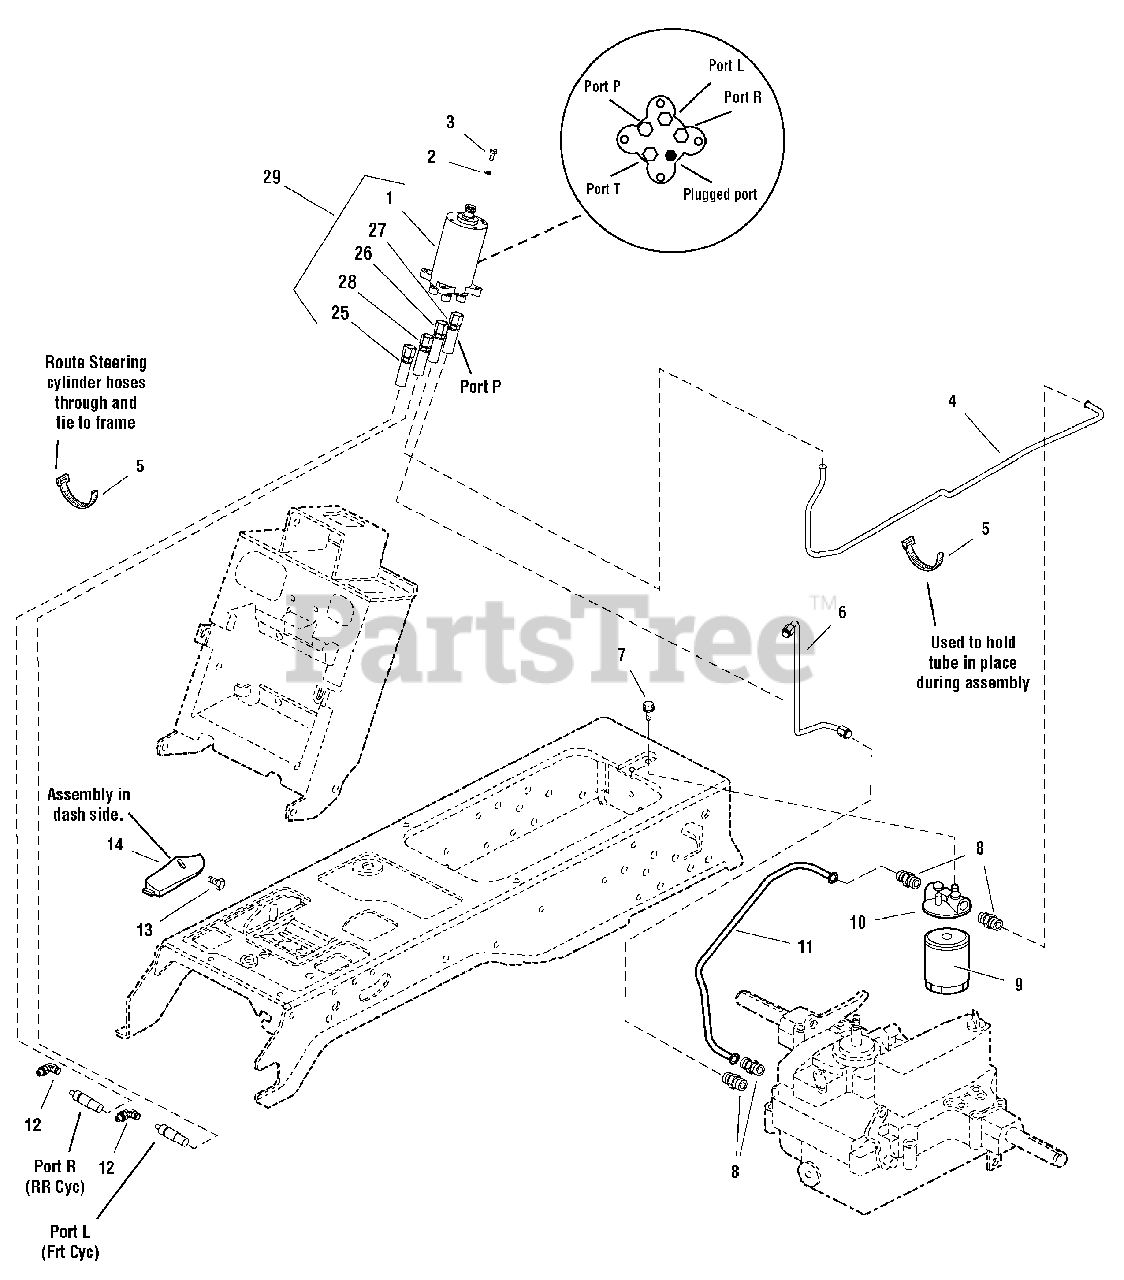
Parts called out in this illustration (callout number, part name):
1	POWER STEERING UNIT, 32CC, 4 Ports
2	LOCKWASHER, Spring
3	CAPSCREW, Hex Head
4	TUBE, Hydraulic
5	TIE, Self Locking
6	TUBE, Hydraulic
7	SCREW, Hex Whiz Lock Flange 1/4-20 x 1/2
8	FITTING, Straight
9	FILTER, Oil
10	BASE, Oil Filter
11	TUBE, Hydraulic
12	FITTING, Hose Elbow Perma Push 9/16-18
13	SCREW, Round Head Plastite
14	COVER, Lift
25	HOSE ASSEMBLY, 50"
26	HOSE ASSEMBLY, 18"
27	HOSE ASSEMBLY, 26"
28	HOSE ASSEMBLY, 46"
29	POWER STEERING ASSEMBLY, 32CC, 4 Ports
29	POWER STEERING ASSEMBLY
